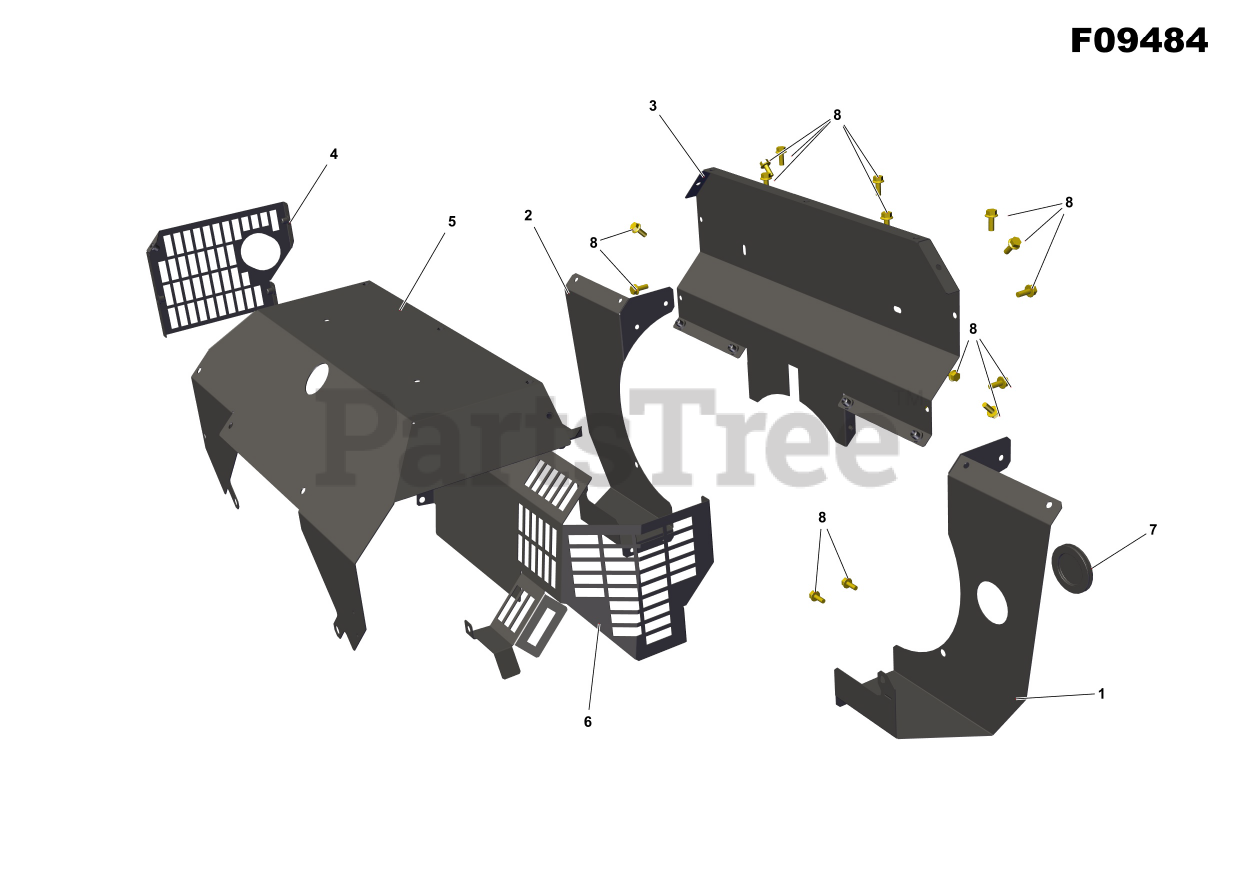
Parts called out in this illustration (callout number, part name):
1	Exhaust air deflector
2	Exhaust air deflector
3	Exhaust air deflector
4	Exhaust air deflector
5	Exhaust air deflector
6	Exhaust air deflector
